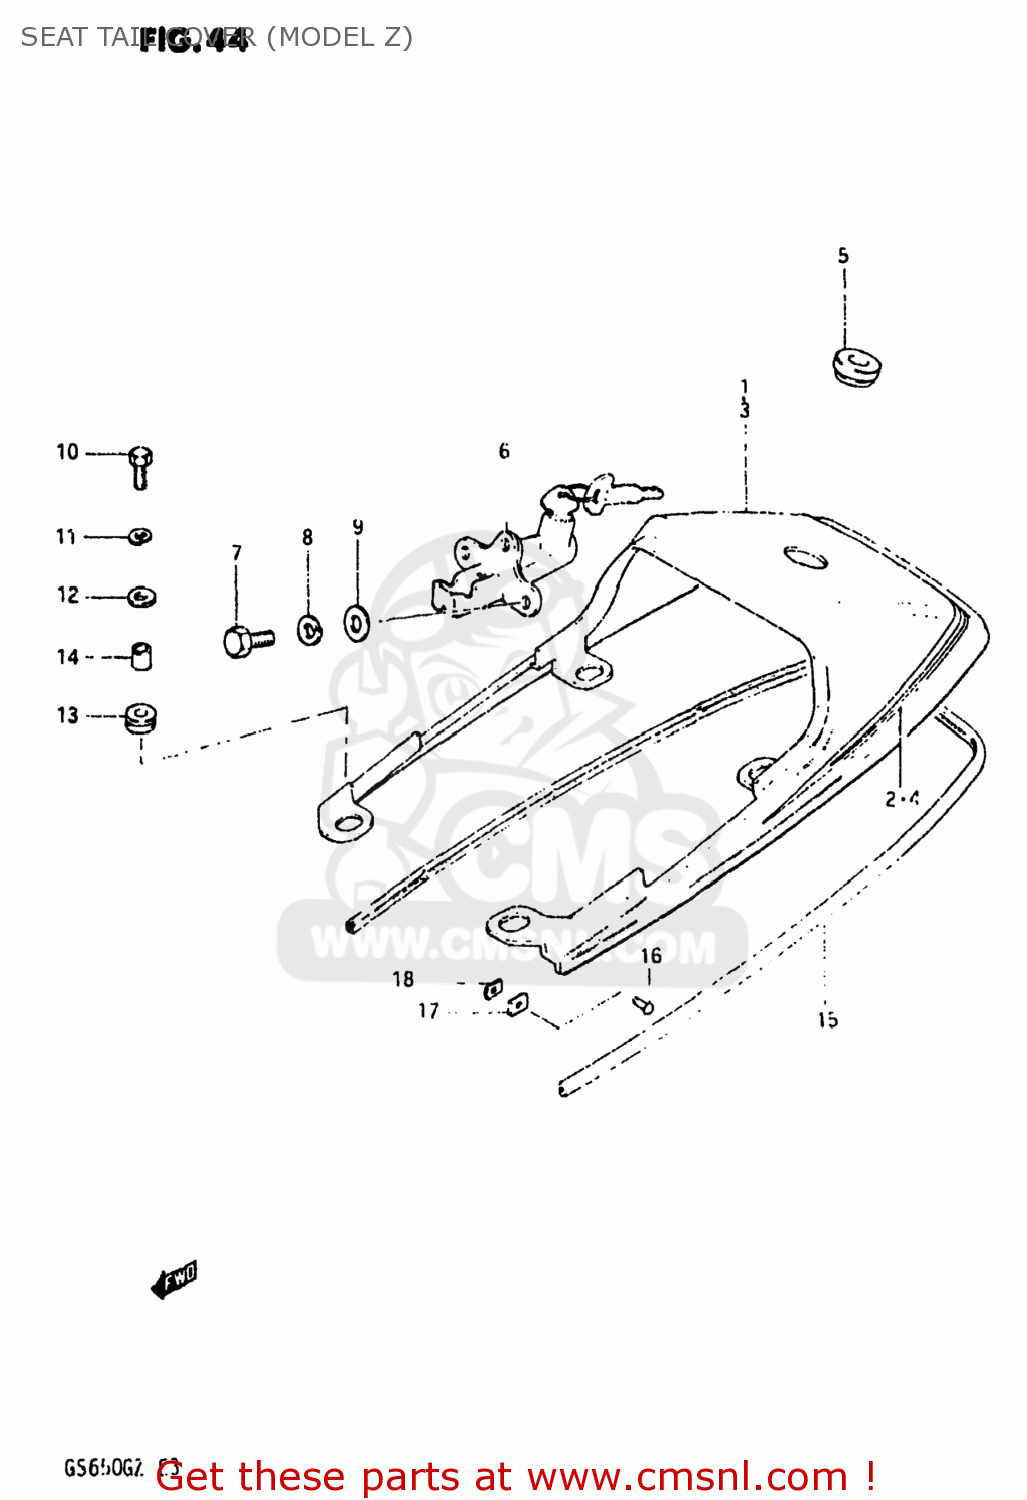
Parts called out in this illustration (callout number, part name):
1	BOX ASSEMBLY,SEAT TAIL
2	TAPE SET,BOX SEAT TAIL
3	COVER ASSEMBLY,SEAT TAIL
4	TAPE SET,BOX SEAT TAIL
5	GROMMET,SEAT LOCK HOLE
6	LOCK SET,SEAT
7	BOLT
8	LOCK WASHER
9	WASHER
10	BOLT
11	LOCK WASHER
12	WASHER(6,5X22X1.6)
13	CUSHION
14	SPACER(6.5X10.5X12)
15	MOLDING,SEAT TAIL COVER
16	RIVET
17	CUSHION,SEAT TAIL
18	NUT
